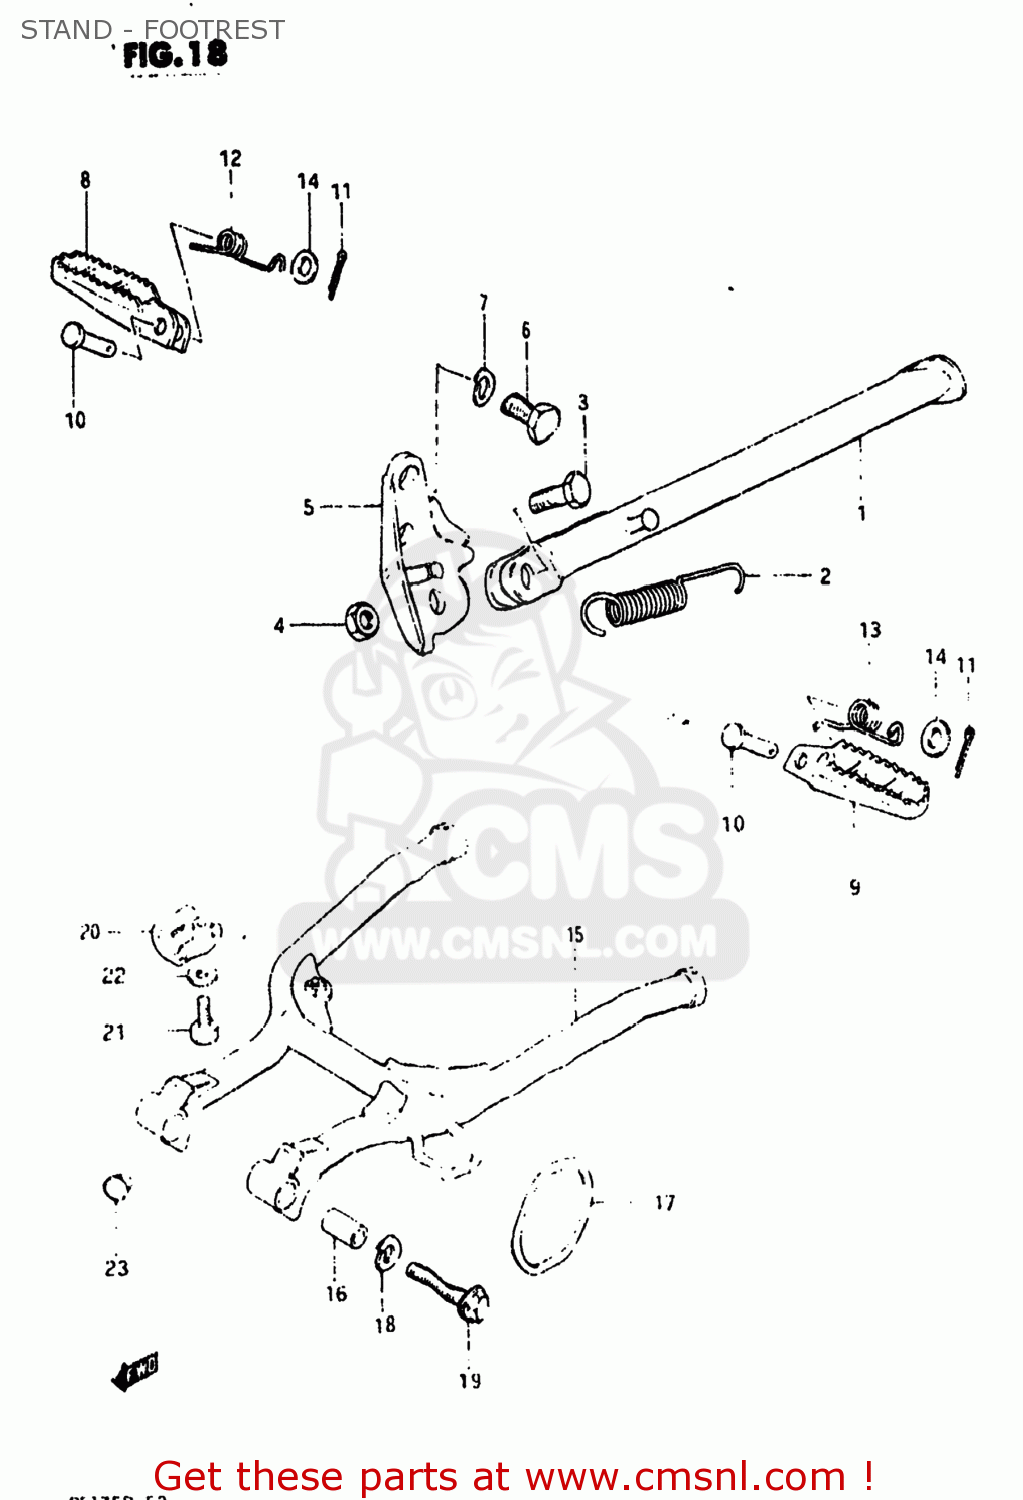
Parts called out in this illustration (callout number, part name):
1	STAND,SIDE
2	SPRING
3	BOLT(10X30)
4	NUT
5	BRACKET,SIDE STAND
6	BOLT(10X19)
7	LOCK WASHER
8	RUBBER,FRONT FOOTREST
9	FOOTREST
10	PIN
11	PIN 20X20
12	SPRING
13	SPRING
14	WASHER
15	STAND,CENTER
16	SPACER(10.5X16X30)
17	O RING CTR STAND
18	LOCK WASHER
19	BOLT
20	PROTECTOR CTR STAND
21	BOLT
22	WASHER
23	CUSHION
